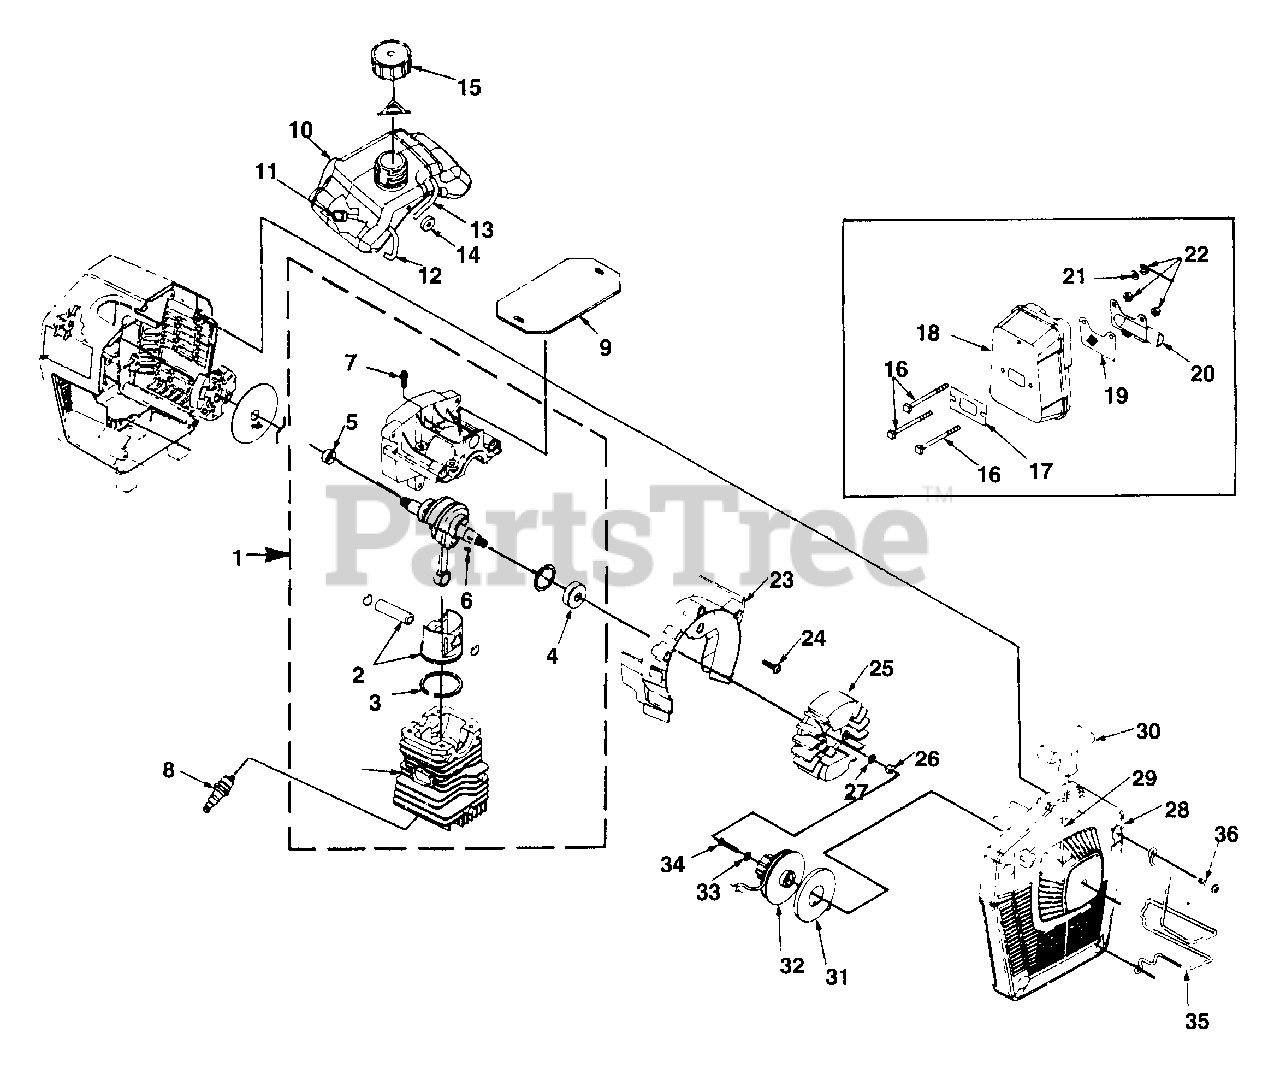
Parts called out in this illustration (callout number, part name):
1	SHORT BLOCK
2	PISTON & PIN
3	RING-Piston
4	SEAL-Shaft
5	SEAL-Crankshaft
6	KEY-Woodruff
7	SCREW-Hex Hd (12-24 X 7/8")
8	SPARK PLUG (CJ6Y)
9	SPACER-Fuel Tank
10	TANK-Fuel
11	FILTER-Fuel
12	TUBING-Rubber (10")
13	TUBING-Rubber (9 1/4")
14	SPACER-Fuel Tank
15	FUEL CAP ASSEMBLY
16	SCREW-Square Hex (10-23 X 2 1/2")
17	GASKET-Muffler
18	MUFFLER
19	SCREEN-Spark Arrestor
20	COVER-Exhaust
21	WASHER-Flat (#10)
22	NUT-Locking Hex (10-32)
23	SCROLL-Fan
24	SCREW-Thread Form (10-24 X 3/4")
25	ROTOR ASSEMBLY
26	NUT-Hex Jam (3/8-24)
27	WASHER-Lock (3/8")
28	STARTER-Complete
29	ROPE-Starter
30	GRIP-Starter
31	SPRING & CONTAINER (L.H.)
32	PULLEY-Starter
33	WASHER (#10)
34	SCREW-Thread Form (#10)
35	GUARD-Wire
36	SCREW-Thread Form (10-24 X 7/8")
